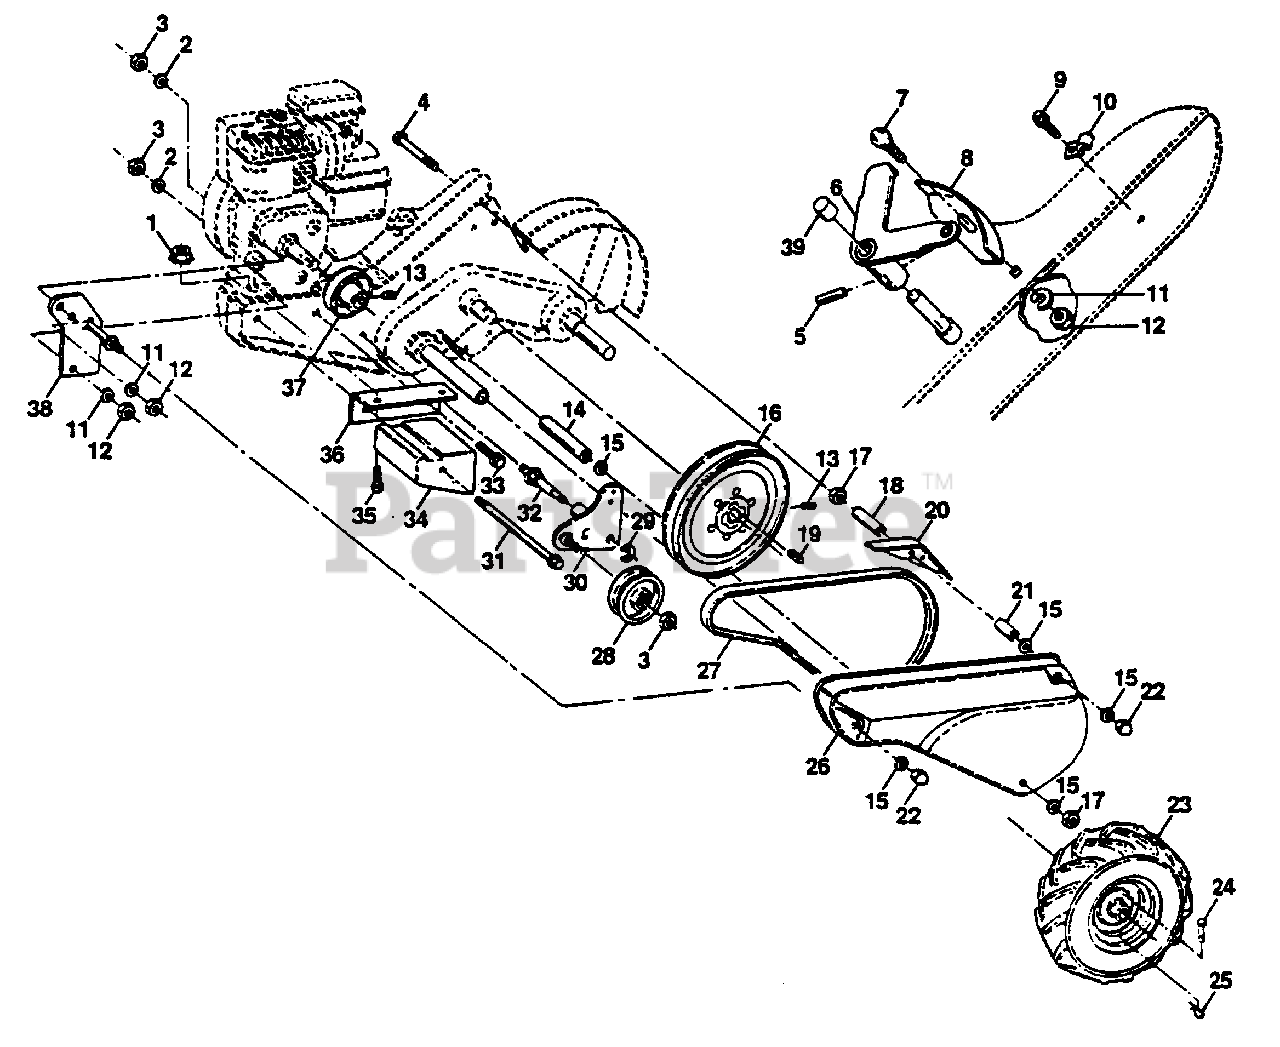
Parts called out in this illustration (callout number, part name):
1	Nut, Keps 5/16-18 (AYP part number)
2	Washer, Lock 3/8 (AYP part number)
3	Nut, Hex 3/8-16 (AYP part number)
4	Bolt, Hex 5/16-18 x 4-1/4 (AYP part number)
5	Pin, Roll (AYP part number)
6	Lever, Shift
7	Bolt, Carriage 1/4-20 x 1/2 Gr. 5 (AYP part number)
8	Plate, Shift Indicator (AYP part number)
9	Screw, Hex, Washer Head, Slotted #10-24 x 1/2 (AYP part number)
10	Clip (AYP part number)
11	Washer, Lock 1/4 (AYP part number)
12	Nut, Hex 1/4-20 (AYP part number)
13	Screw, Set, Hex 5/16-18 x 3/8 (AYP part number)
14	Spacer, Split 0.327 x 0.42 x 2.68 (AYP part number)
15	Washer 11/32 x 11/16 x 16 Ga. (AYP part number)
16	Sheave, Transmission (AYP part number)
17	Nut, Hex 5/16-18 (AYP part number)
18	Spacer, Split 0.327 x 0.42 x 1.75 (AYP part number)
19	Key, Square 3/16 x 1-1/8 (AYP part number)
20	Guard, Pinch Point (AYP part number)
21	Spacer, Split 0.327 x 0.42 x 1.627 (AYP part number)
22	Nut, Cap 5/16-18 (AYP part number)
23	Tire (AYP part number)
24	Rivet, Drilled (AYP part number)
25	Clip, Hairpin (AYP part number)
26	Guard, Belt (AYP part number)
27	Belt, V (AYP part number)
28	Pulley, Idler (AYP part number)
29	Ring, Klip (AYP part number)
30	Bracket, Idler (AYP part number)
31	Bolt, Hex 5/16-16 x 12 (AYP part number)
32	Shaft, Idler Arm (AYP part number)
33	Bolt, Hex 3/8-16 x 1 (AYP part number)
34	Counterweight, L. H. (AYP part number)
35	Bolt, Hex 5/16-18 x 1-1/2 (AYP part number)
36	Bracket, Reinforcement, L. H. (AYP part number)
37	Sheave, Engine (AYP part number)
38	Bracket, Guard Belt
39	Cap, Plunger Blk (AYP part number)
